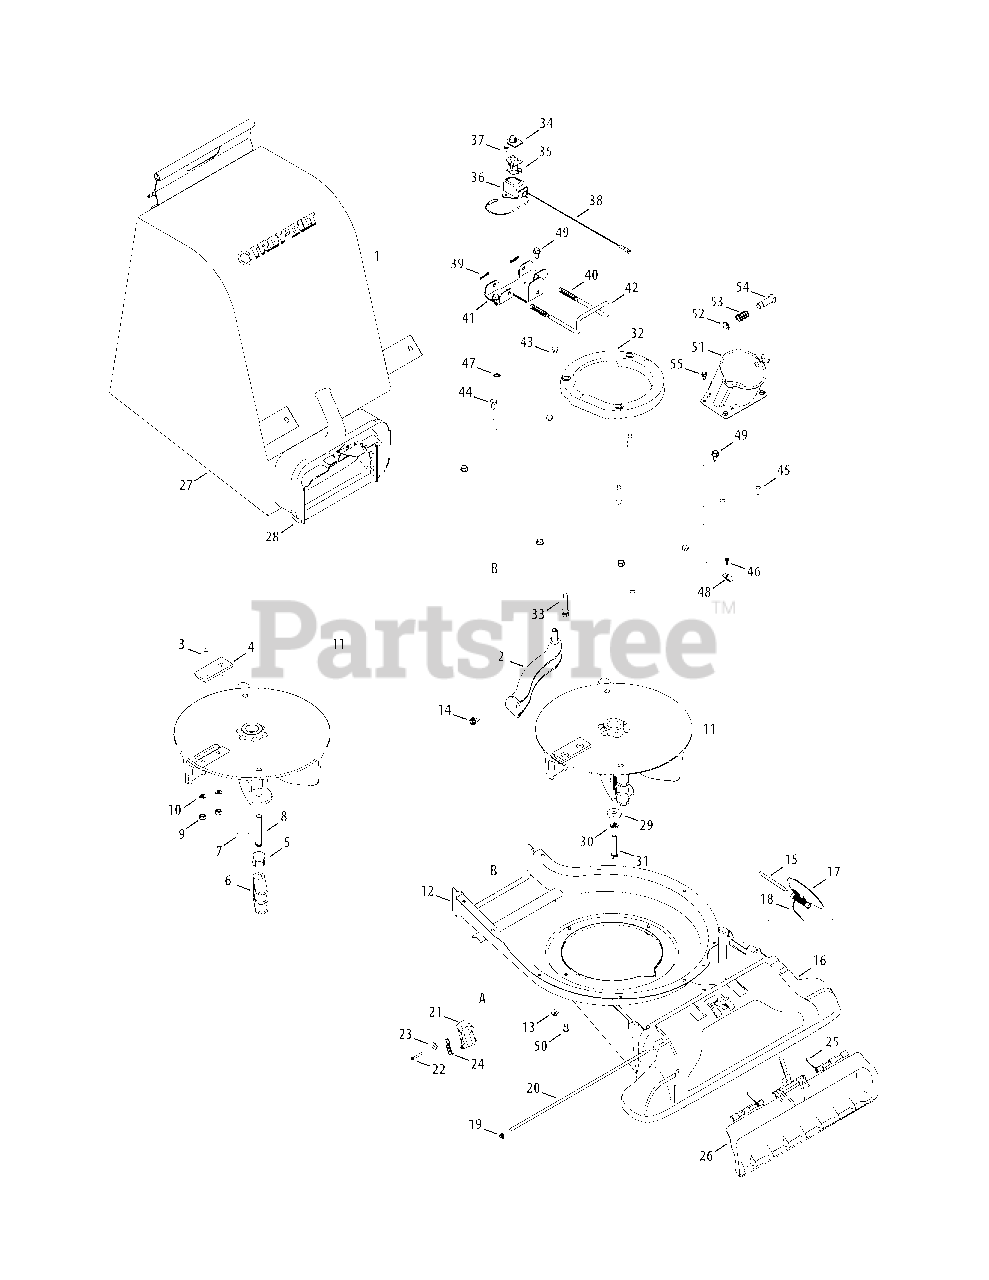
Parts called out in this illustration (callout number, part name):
1	Bag Assembly
2	Screen Assembly
3	Hex Screw, 5/16-24 x 1.0
4	Chipper Blade
7	Spiral Pin
8	Clevis Pin
9	Lock Nut, 5/16-24
10	Lock Washer, 5/16
11	Impeller Assembly (Incl. Ref.# 3 - 10)
12	Lower Flail Housing
13	Flange Lock Nut, 5/16-18
14	Screw, 5/16-18 x.500
17	Base Adapter Door
18	Torsion Spring
19	Cap Speed Nut, 1/4
20	Pivot Rod
21	Nozzle Door Lever
22	Hex Screw, #8-18 x 1.25
23	Shoulder Spacer
24	Extension Spring
25	Nozzle Door Torsion Spring
26	Nozzle Door
28	Chute Assembly
29	Flat Washer, .375 ID x 1.25 OD
30	Lock Washer, 3/8
31	Hex Cap Screw, 3/8-24 x 2.75
32	Engine Spacer Assembly
33	Screw, 3/8-16 x 1.875
34	Switch Cover
35	Safety Switch
36	Safety Switch Cover
37	Hex Washer Screw, #10-16 x.50
38	Wire Harness
39	Cotter Pin
40	Compression Spring
41	Mounting Bracket
43	Hex Cap Screw, 5/16-18 x 4.5
44	Hex Cap Screw, 5/16-18 x.625
45	Screw, #12-16 x.750
46	Screw, #10 - 16 x.500
47	External L-Washer, 5/16
48	Speed Nut
49	Hex Index Screw, 5/16-12 x.750
50	Shldr. Screw, #12-24 x .30 x .46
51	Hose Base Adapter Assembly (Incl. Ref.# 52-54)
52	E Ring, .500 Dia
53	Compression Spring
54	Clevis Pin
55	Screw, 1/4-20 x .500
